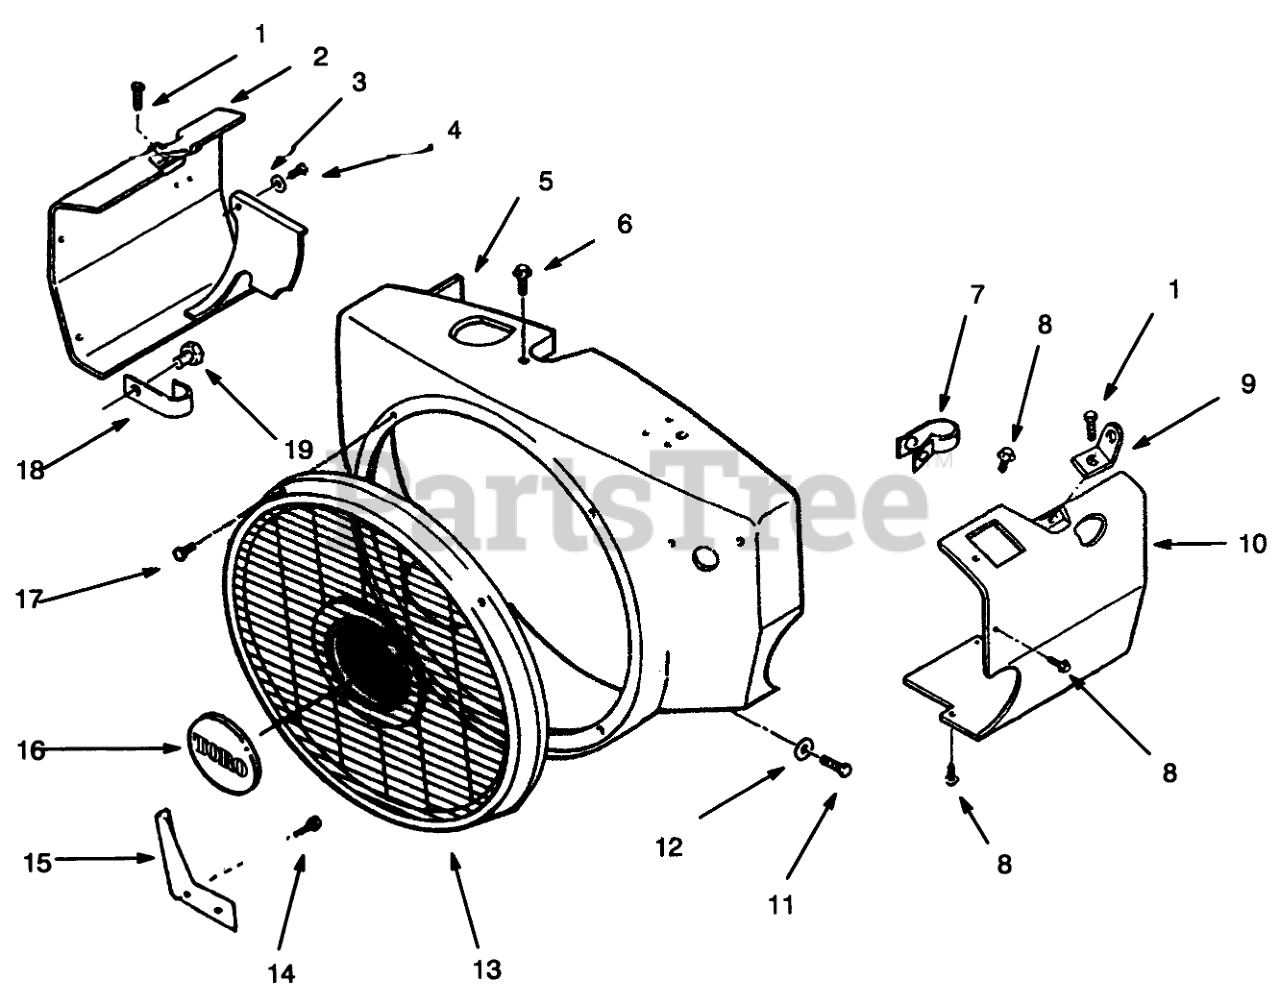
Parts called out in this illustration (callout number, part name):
1	SCREW-HWH
2	LH AIR CYLINDER HSG
3	Bolt
4	SCREW-HH
5	HOUSING
6	HEX HD CAPSCREW
7	Clamp
8	Bolt
9	Bracket-Lifting
10	RH AIR CYLINDER HSG
11	Bolt
12	Washer
13	GUARD-STATIONARY
14	SCREW - THREAD CUTTING
15	BRACKET
16	NAME-PLATE TORO LOGO
17	SCREW-PAN HEAD
18	Clip
19	SCREW-HWH
